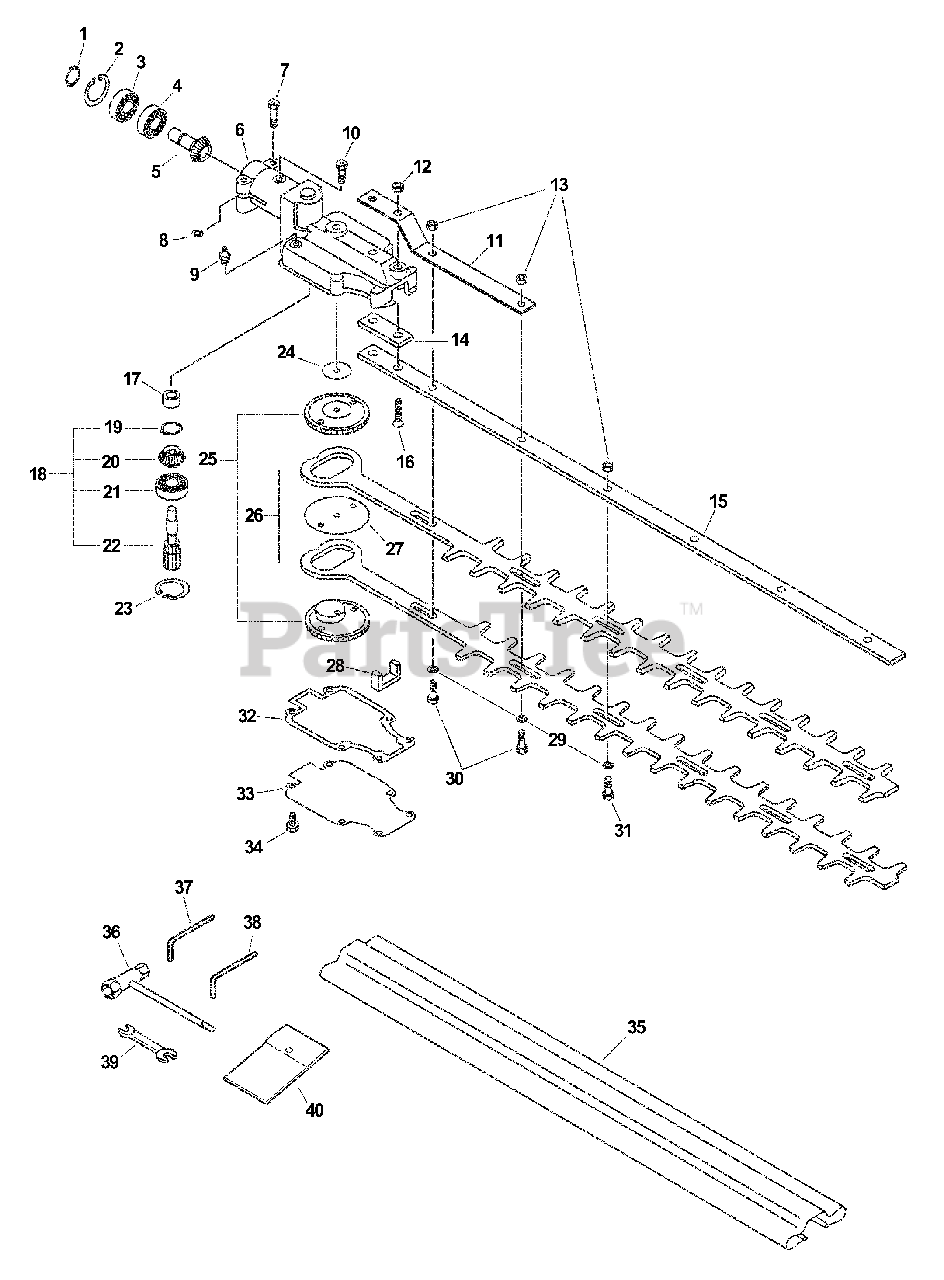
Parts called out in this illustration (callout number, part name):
1	RING, RETAINING Ø24
2	RING, SNAP Ø12
3	BEARING, BALL 6901Z
4	BEARING, BALL 6901
5	GEAR, BEVEL
6	CASE, GEAR - UPPER
7	BOLT 5×28
9	FITTING, GREASE
10	BOLT 5×12
11	PLATE, ANGLE
12	NUT, HEX M6
14	SPACER
15	BAR, FRAME
16	SCREW 6×35
17	BEARING, NEEDLE
18	SPUR GEAR ASSY
19	RING, RETAINING
20	GEAR, BEVEL - DRIVEN
21	BEARING, BALL 6901
22	GEAR, PINION
23	RING, RETAINING Ø24
24	WASHER 6.5×30×0.2
25	GEAR, SPUR
26	BLADE, TRIMMER
27	WASHER 6.7×54×0.38
28	PACKING, FELT
29	WASHER 6.5×15.5×0.6
30	BOLT 6×20
32	GASKET, GEAR CASE
33	LID, GEAR CASE
34	BOLT 4×12
35	COVER, BLADE
36	T-WRENCH 17x-19 L200
37	WRENCH, ALLEN 4 MM
38	WRENCH, ALLEN 3 MM
39	SPANNER 8×10
40	BAG, TOOL
